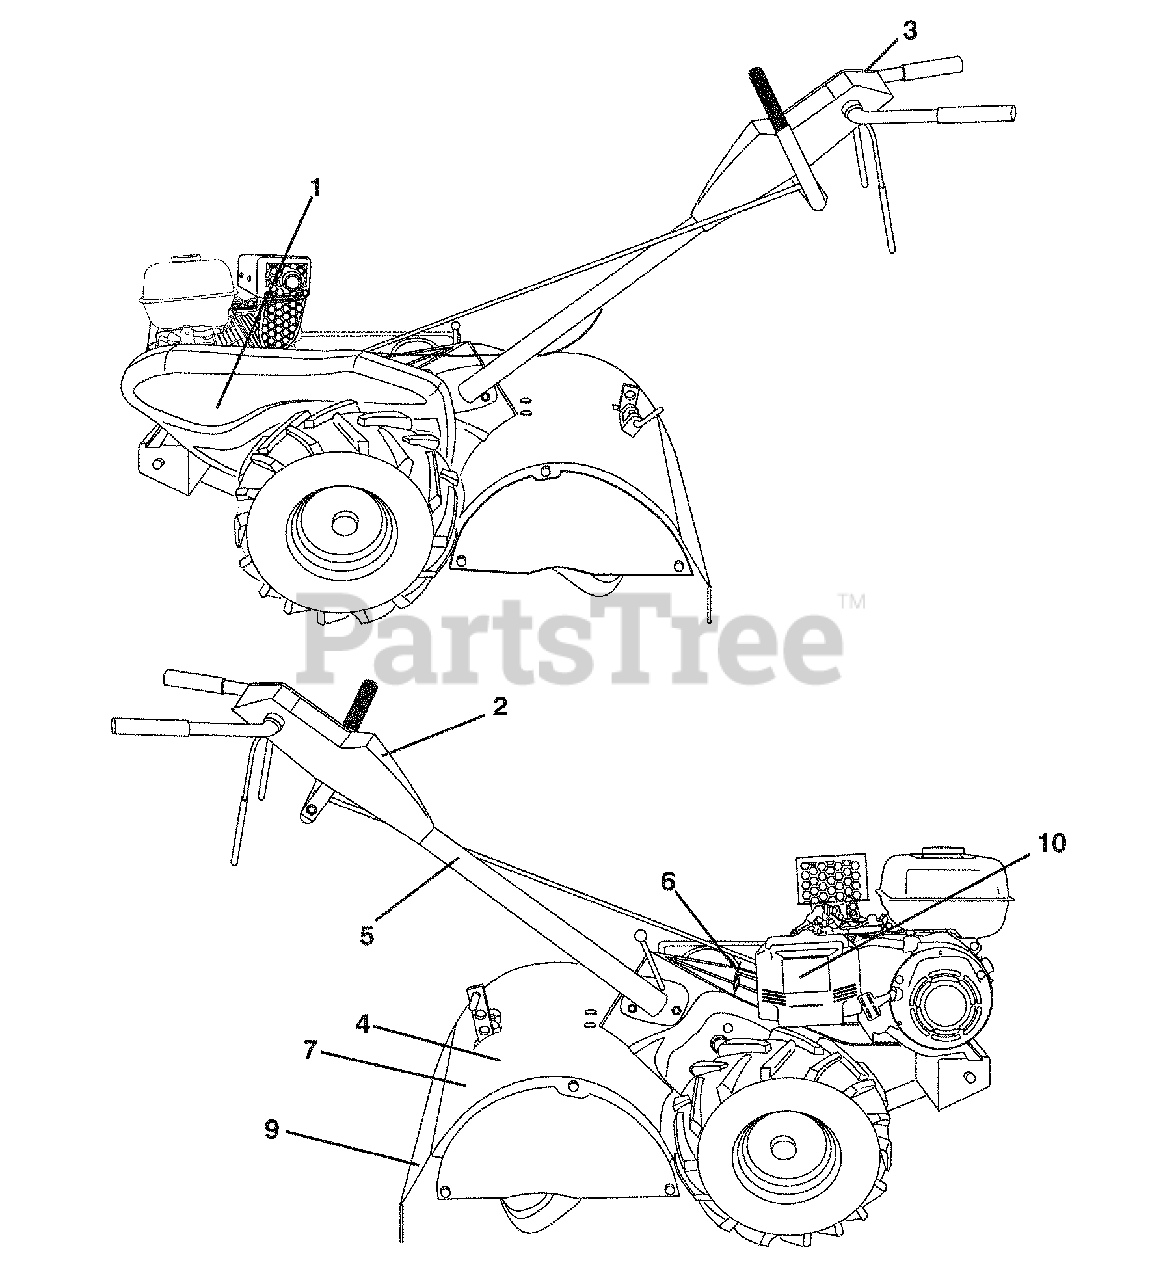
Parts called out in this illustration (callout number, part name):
1	Decal, Belt Guard
2	Decal, Console
3	Decal, Console Instruction
4	Decal, Tine Shield
5	Decal, Hand Placement
6	Decal, Shift Indicator
7	Decal, Warning
9	Decal, Warning, Rotating Tines
10	Decal, Engine, AC
